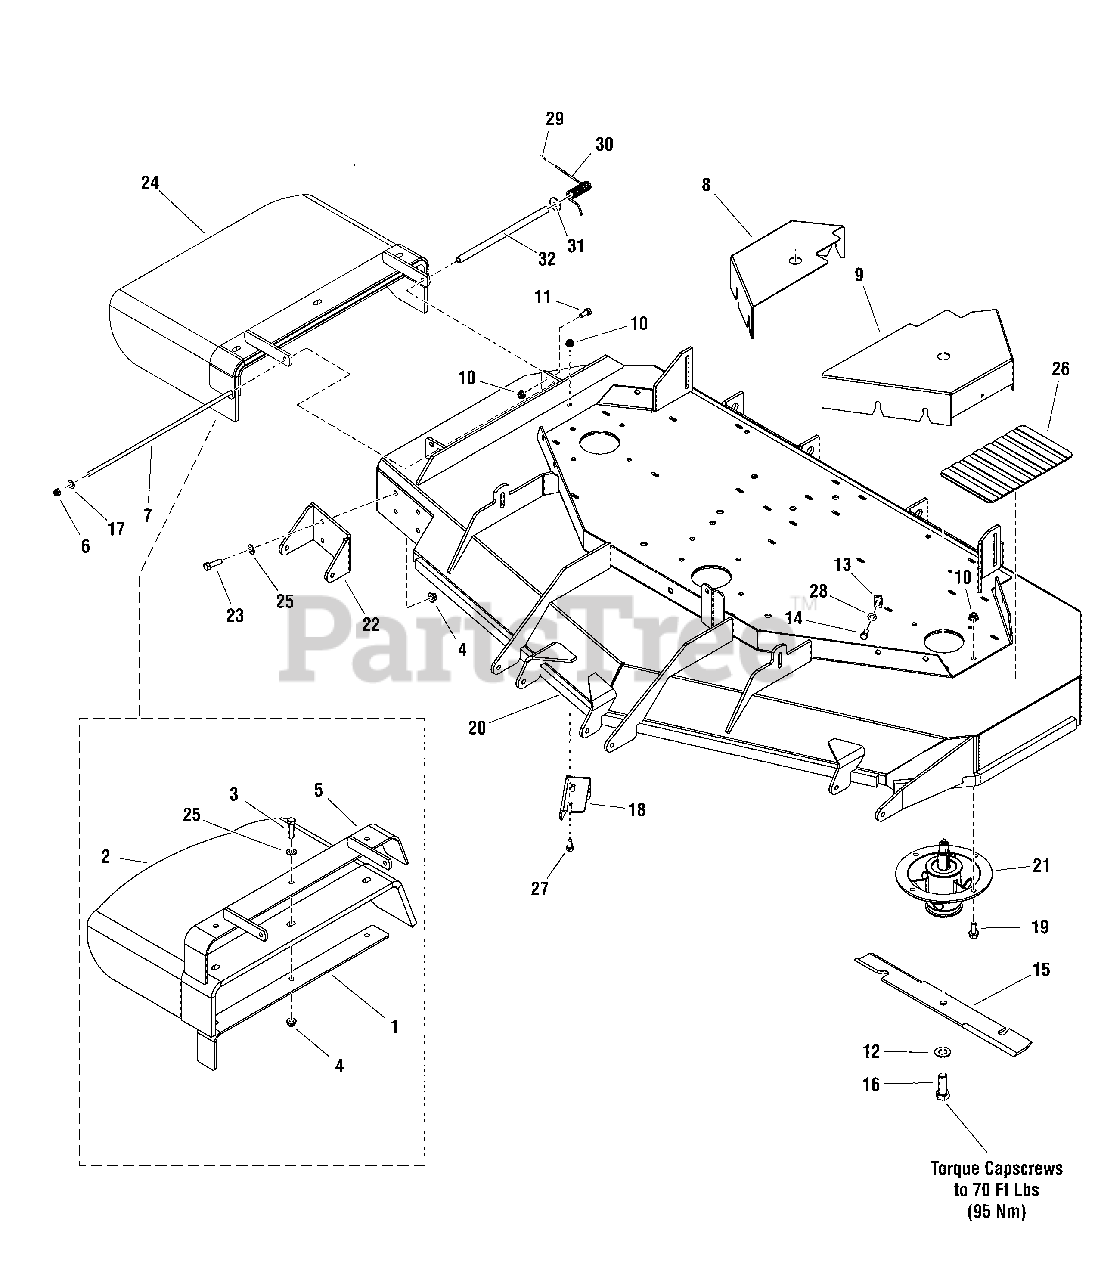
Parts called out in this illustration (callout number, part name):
1	SUPPORT, DISCHARGE CHUTE, 61/72 - BLK
2	CHUTE, DISCHARGE, BEND RUBBER (SV)
3	BOLT, 3/8-16 X 1-1/2 GD5 YZ
4	NUT, 3/8-16 HEX NYLOCK FLANGE
5	WELD, FRAME CHUTE, 61 - BLK
6	NUT, 5/16-24 HEX NYLON LOCK
7	ROD MOUNT, CHUTE 61"
8	GUARD, 61" - RH - ORG
9	GUARD 61" - LH - ORG
10	NUT, 5/16-18 HEX NYLOCK FLANGE
11	SCREW-HEX WZ LOCK FLNG 5/16-18X0.750BLK
12	WASHER, 5/8 GRADE 8, YZ
13	BODY CLIP, 5/16-18-7GA MATERIAL
14	BOLT, 5/16-18 X 1 GD5
15	BLADE, 21 X .25 X 2.5, 1 X 3.5 (SET OF 3)
16	BOLT, 5/8-11 X 1-3/4 GD8
17	WASHER, 5/16" SAE
18	PLATE, DEFLECTOR - BLK
19	BOLT, 5/16-18 X 1 1/4 FLANGE
21	ASSM, SPINDLE, LOW PROFILE
22	PLATE, BRACKET, ANTI SCALP - ORANGE
23	BOLT, 3/8-16 X 1 GD5
24	PURCHASE INDIVIDUAL REPLACEMENT PARTS
25	WASHER, 3/8 SAE
26	SAFETY WALK, 9.75 X 6.00
27	BOLT, 5/16-18 X 3/4, CARRIAGE
28	WASHER, 5/16 GRADE 9, FLAT
29	CAP, PROTECTOR, .120 ID
30	SPRING, TORSION
31	WASHER, 5/16 FENDER
32	TUBE, 1/2 X 3/8 X 10.75 BLACK POLY
